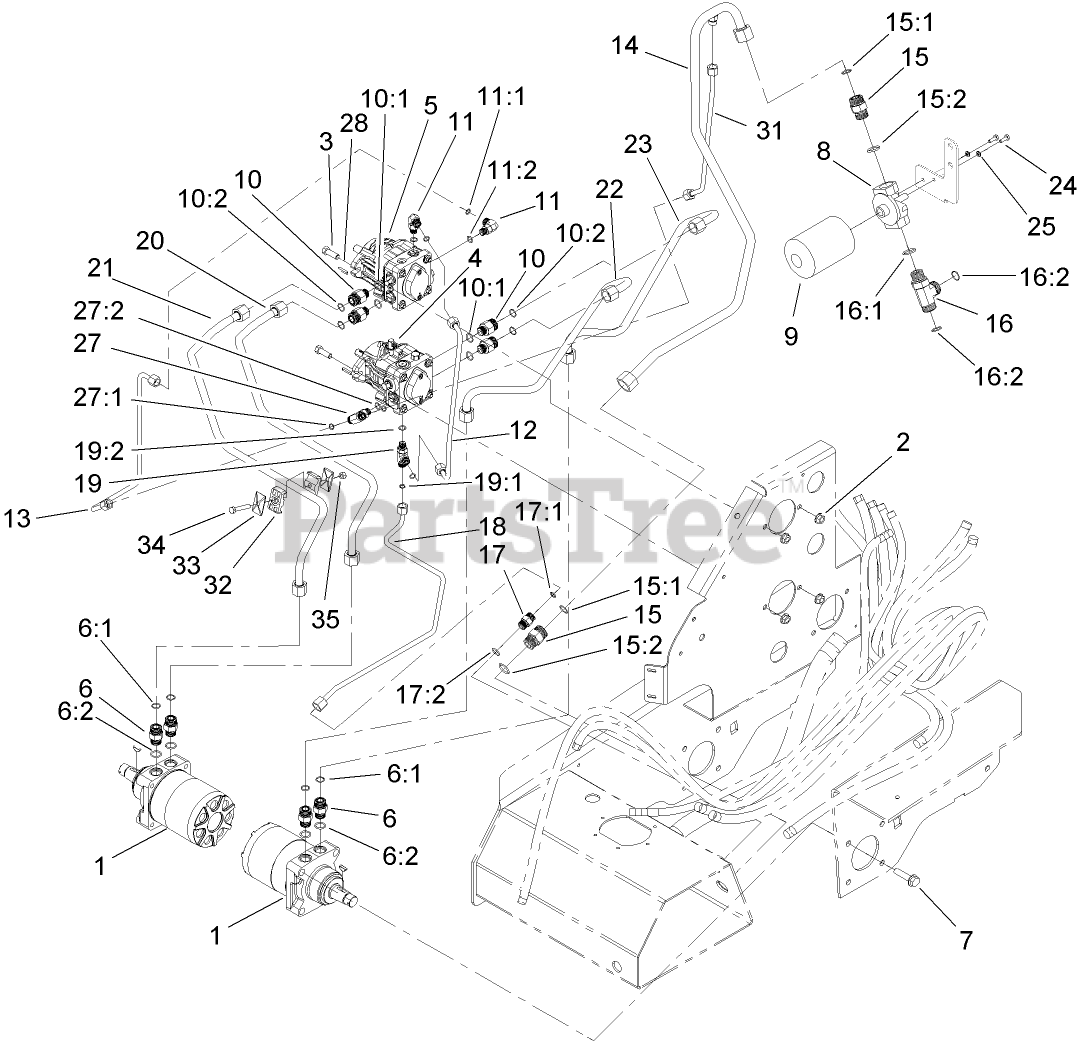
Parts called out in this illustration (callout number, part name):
1	HYD WHEEL MOTOR ASM
2	NUT-HF
3	SCREW-HH
4	PUMP-HYD
5	PUMP-HYD
6	FITTING-STRAIGHT
6:1	O-RING
6:2	O-RING
7	SCREW-HHF
8	HEAD-FILTER
9	FILTER-OIL, TRANSMISSION
10	FITTING-STR
10:1	O-RING
10:2	O-RING
11	FITTING-ELBOW, 90 DEG
11:1	O-RING
11:2	O-RING
12	HYD TUBE ASM
13	HYD TUBE ASM
14	HYD TUBE ASM
15	FITTING-STR
15:1	O-RING
15:2	O-RING
16	FITTING-TEE
16:1	O-RING
16:2	O-RING
17	FITTING-STRAIGHT
17:1	O-RING
17:2	O-RING
18	HYD TUBE ASM
19	FITTING-TEE
19:1	O-RING
19:2	O-RING
20	HYD TUBE ASM
21	HYD TUBE ASM
22	HYD TUBE ASM
23	HYD TUBE ASM
24	SCREW-HH
25	WASHER-LOCK
27	ADAPTER
27:1	O-RING
27:2	O-RING
28	KEY-PUMP
31	HYD TUBE ASM
32	CLAMP-TUBE
33	COVERPLATE
34	SCREW-HH
35	NUT-LOCK, NI
